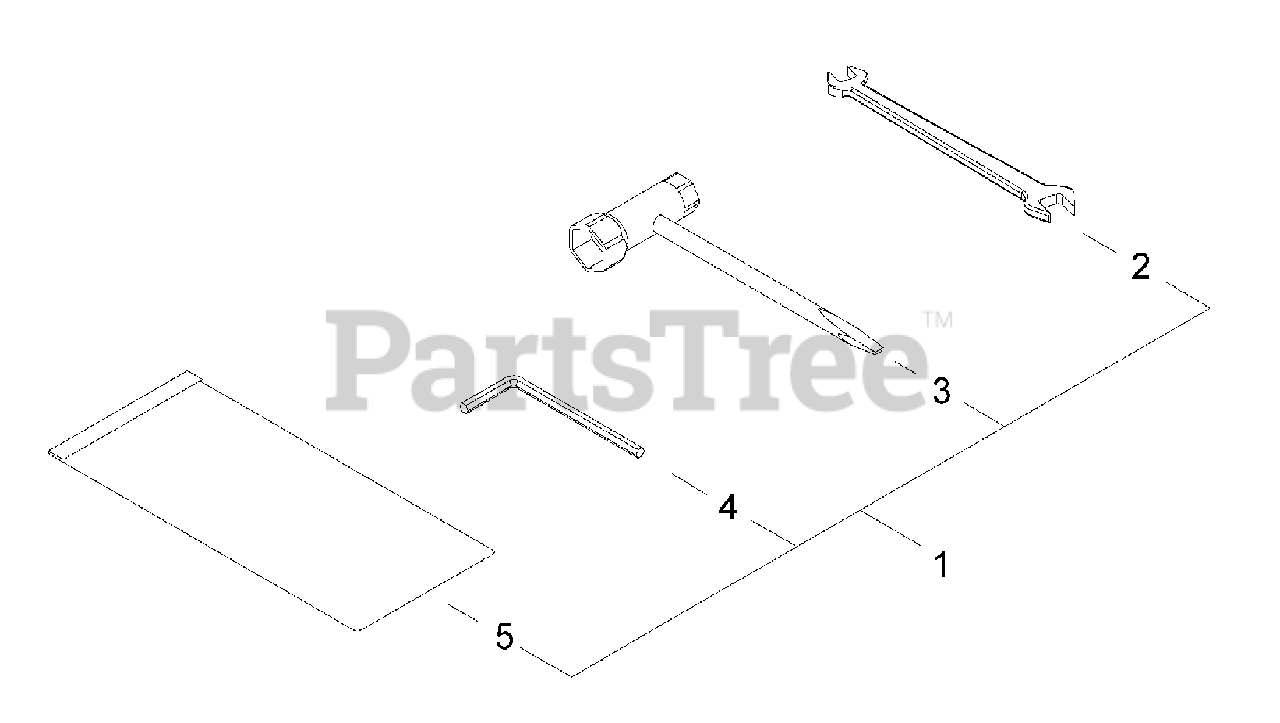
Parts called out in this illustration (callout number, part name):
1	TOOL KIT, SERVICE
2	SPANNER 8×10
3	T-WRENCH 16×13
4	WRENCH, ALLEN 4 MM
5	BAG, TOOL
